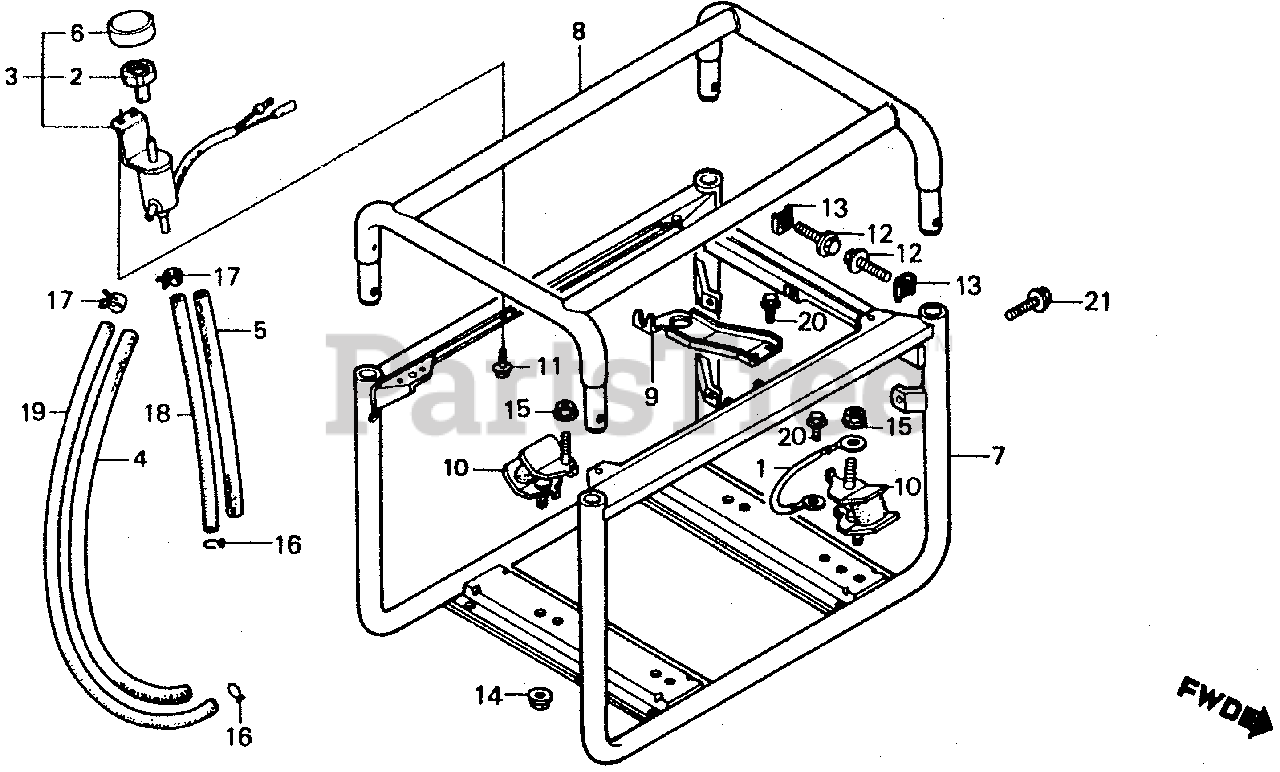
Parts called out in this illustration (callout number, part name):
1	CABLE, GROUND
2	FILTER ASSY., SOLENOID VALVE
3	VALVE ASSY., CONTROL (NOT AVAILABLE)
4	PROTECTOR, TUBE (9X390) (NOT AVAILABLE)
5	PROTECTOR, TUBE (9X130)
6	CAP, AIR FILTER
7	FRAME (LOWER)
8	FRAME (UPPER)
9	STAY, BUMP STOP
10	RUBBER (LOWER)
11	BOLT, FLANGE (5X10)
12	BOLT, FLANGE (8X20)
13	WASHER, FRAME JOINT
14	NUT, FLANGE (8MM)
15	NUT, FLANGE (10MM)
16	CLIP, TUBE (B7)
17	CLIP, TUBE (D8)
18	BULK HOSE, VACUUM (3.5X1000) (3.5X140)
19	BULK HOSE, VACUUM (3.5X1000) (3.5X400)
20	BOLT, FLANGE (6X10)
21	BOLT, FLANGE (6X12)
